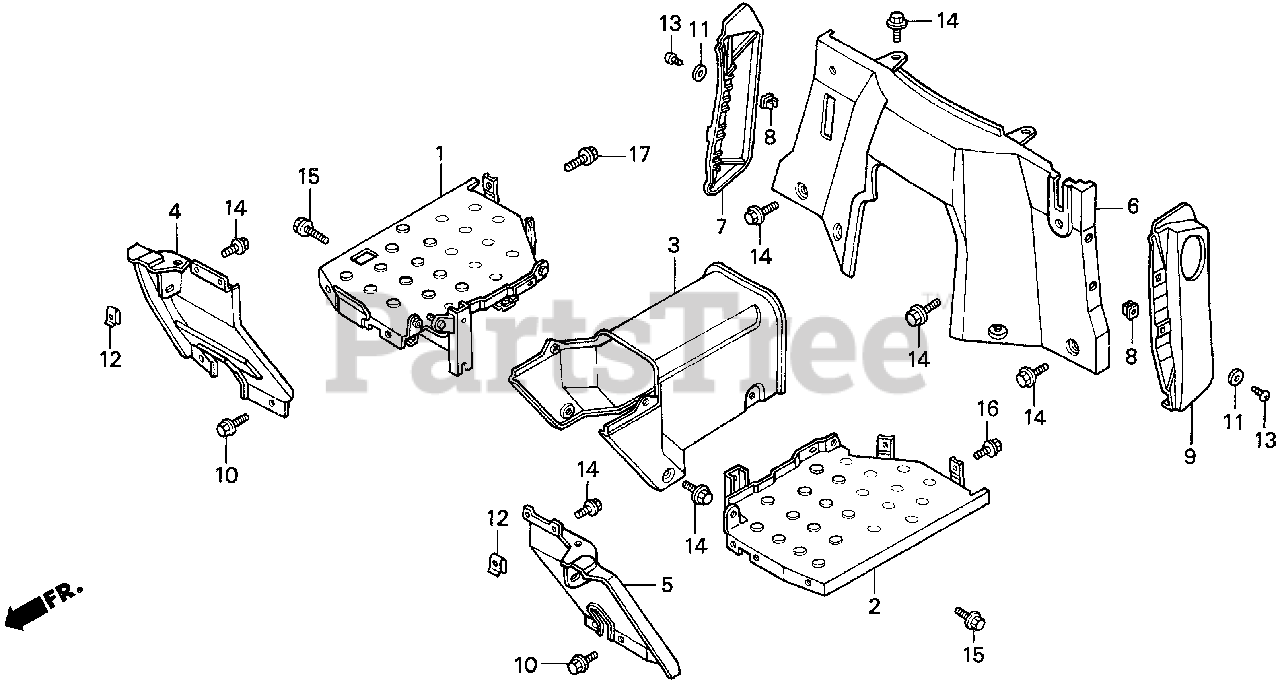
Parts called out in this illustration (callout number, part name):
1	STEP, R. *R165* (JOLLY RED)
2	STEP, L. *R165* (JOLLY RED)
3	FLOOR *R165* (JOLLY RED)
4	FENDER, R. FR. *R165* (JOLLY RED)
5	FENDER, L. FR. *R165* (JOLLY RED)
6	COVER, RR. *R165* (JOLLY RED)
7	COVER, R. SIDE *R165* (JOLLY RED)
8	NUT, NYLON (6MM)
9	COVER, L. SIDE *R165* (JOLLY RED)
10	BOLT, FENDER (6X18)
11	WASHER (6MM)
12	NUT, CLIP (6MM)
13	SCREW, TAPPING (6X20)
14	BOLT, FLANGE (6X12)
15	BOLT, FLANGE (8X14)
16	BOLT, FLANGE (8X16)
17	BOLT, FLANGE (8X25)
